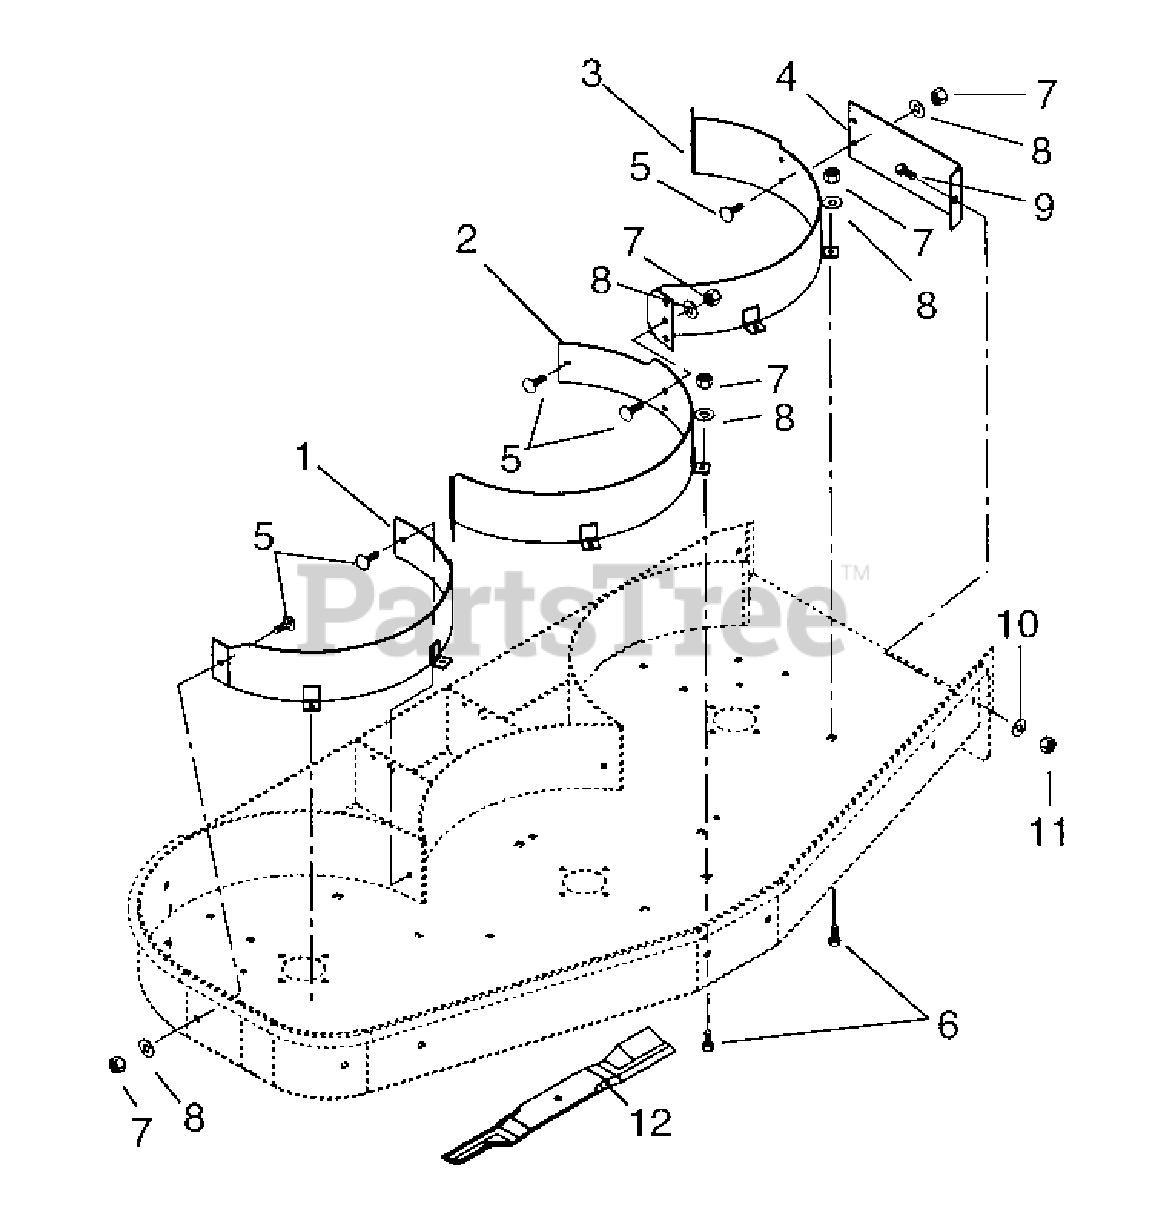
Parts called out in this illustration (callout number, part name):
1	Baffle, Weldment Left (50")
1	Baffle, Weldment Left (60")
1	Baffle, Weldment Left (72")
2	Baffle, Weldment Center (50")
2	Baffle, Weldment Center (60")
2	Baffle, Weldment Center (72")
3	Baffle, Mulching Right (50")
3	Baffle, Mulching Right (60")
3	Baffle, Mulching Right (72")
4	Baffle, End Mulching (50")
4	Baffle, End Mulching (60")
4	Baffle, End Mulching (72")
5	Bolt, Round Head Square Neck 5/16-18 x 314
6	Bolt, Hex 5/16-18 x 1 Grade 5
7	Nut, Locking Nylon 5/16-18
8	Washer, Flat Steel 11/32 x 11/16
9	Bolt, Hex 3/8-16 x 1 Grade 5
10	Washer, Flat Steel 3/8 x 7/8
11	Nut, Locking Nylon 3/8-16
12	Blade Mulching (50")
12	Blade Mulching (60")
12	Blade Mulching (72")
